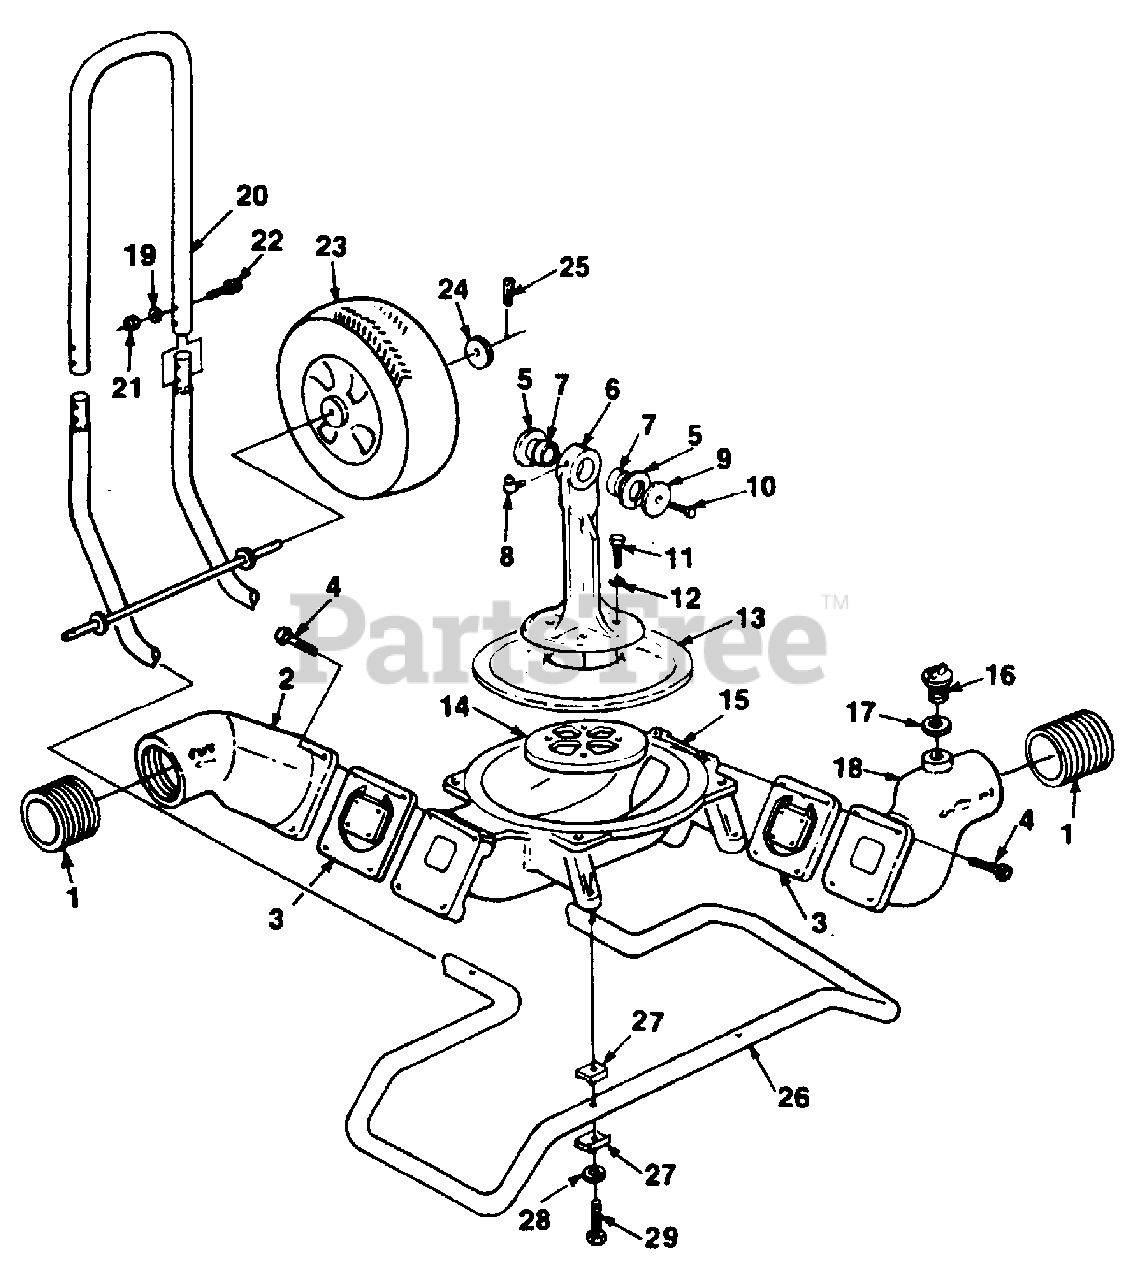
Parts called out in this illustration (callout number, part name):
1	FITTING Pipe
2	FITTING- Discharge
3	VALVE AND INSERT
4	SCREW- Hex hd (5/16-18 x 1")
5	WASHER- Thrust large
6	ROD- Pump
7	BEARING Needle
8	FITTING- Grease
10	SCREW Hex hd. (3/8-16 x 3/4")
11	SCREW- Hex hd. (3/8-16 x 1 1/8")
12	WASHER- Lock (3/8")
13	DIAPHRAGM
14	CAP- Diaphragm
15	BODY- Pump
16	PLUG- Filler
18	FITTING Suction
19	WASHER- Lock (1/4")
20	HANDLE Pump
21	NUT (1/4-20")
22	SCREW- Hex hd (1/4-20 x 1 1/2")
24	WASHER- Flat
25	PIN- Cotter (3/32 x 1 1/8")
26	PUMP SUPPORT 2"
27	SADDLE 1" Pipe
28	WASHER- Lock (5/16")
29	SCREW- Hex hd. (5/16-18 x 2")
